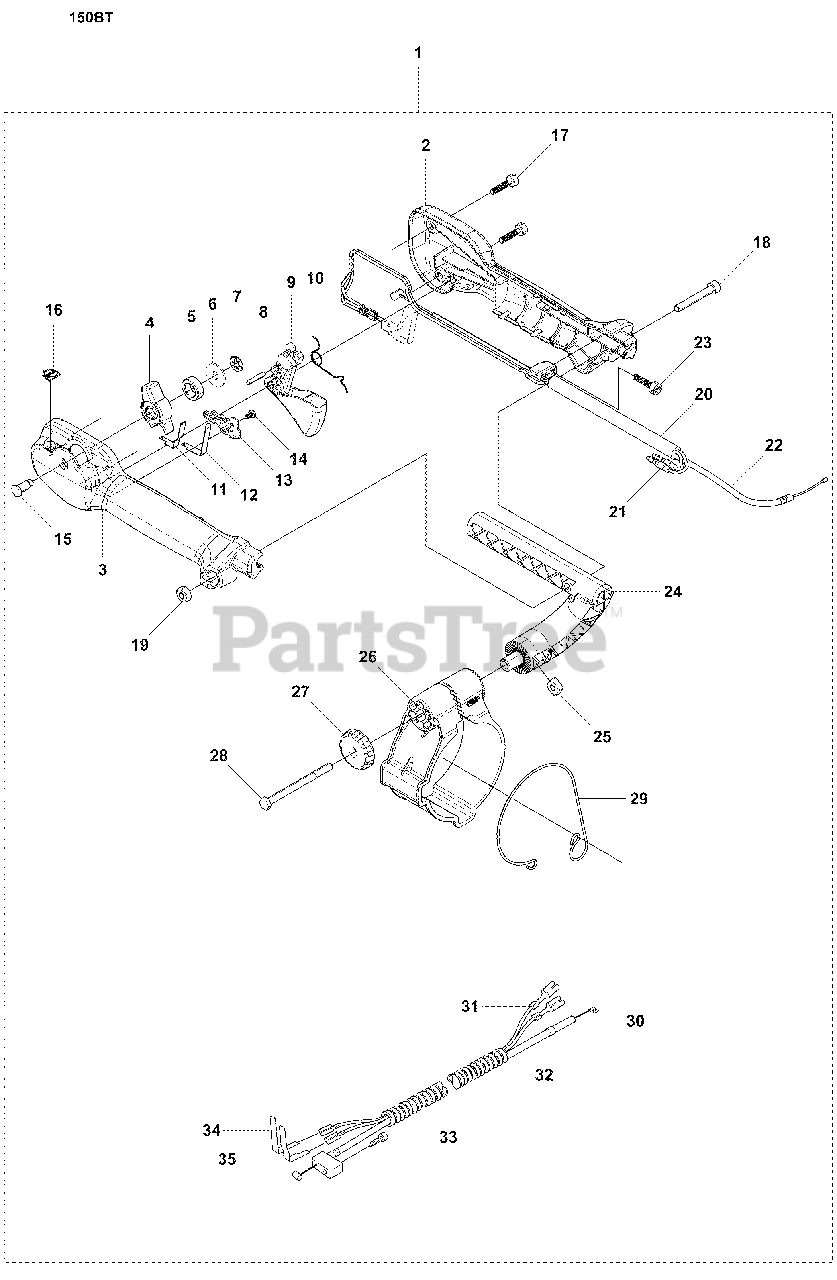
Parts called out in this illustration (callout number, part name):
1	HANDLE ASSY.
5	SPRING RUBBER
9	%THROTTLE TRIGGER
11	CONTACT SPRING
12	CONTACT SPRING
18	%SCREW
24	BRACKET
26	HOLDER TH
34	CONTACT SPRING
35	CONTACT SPRING
